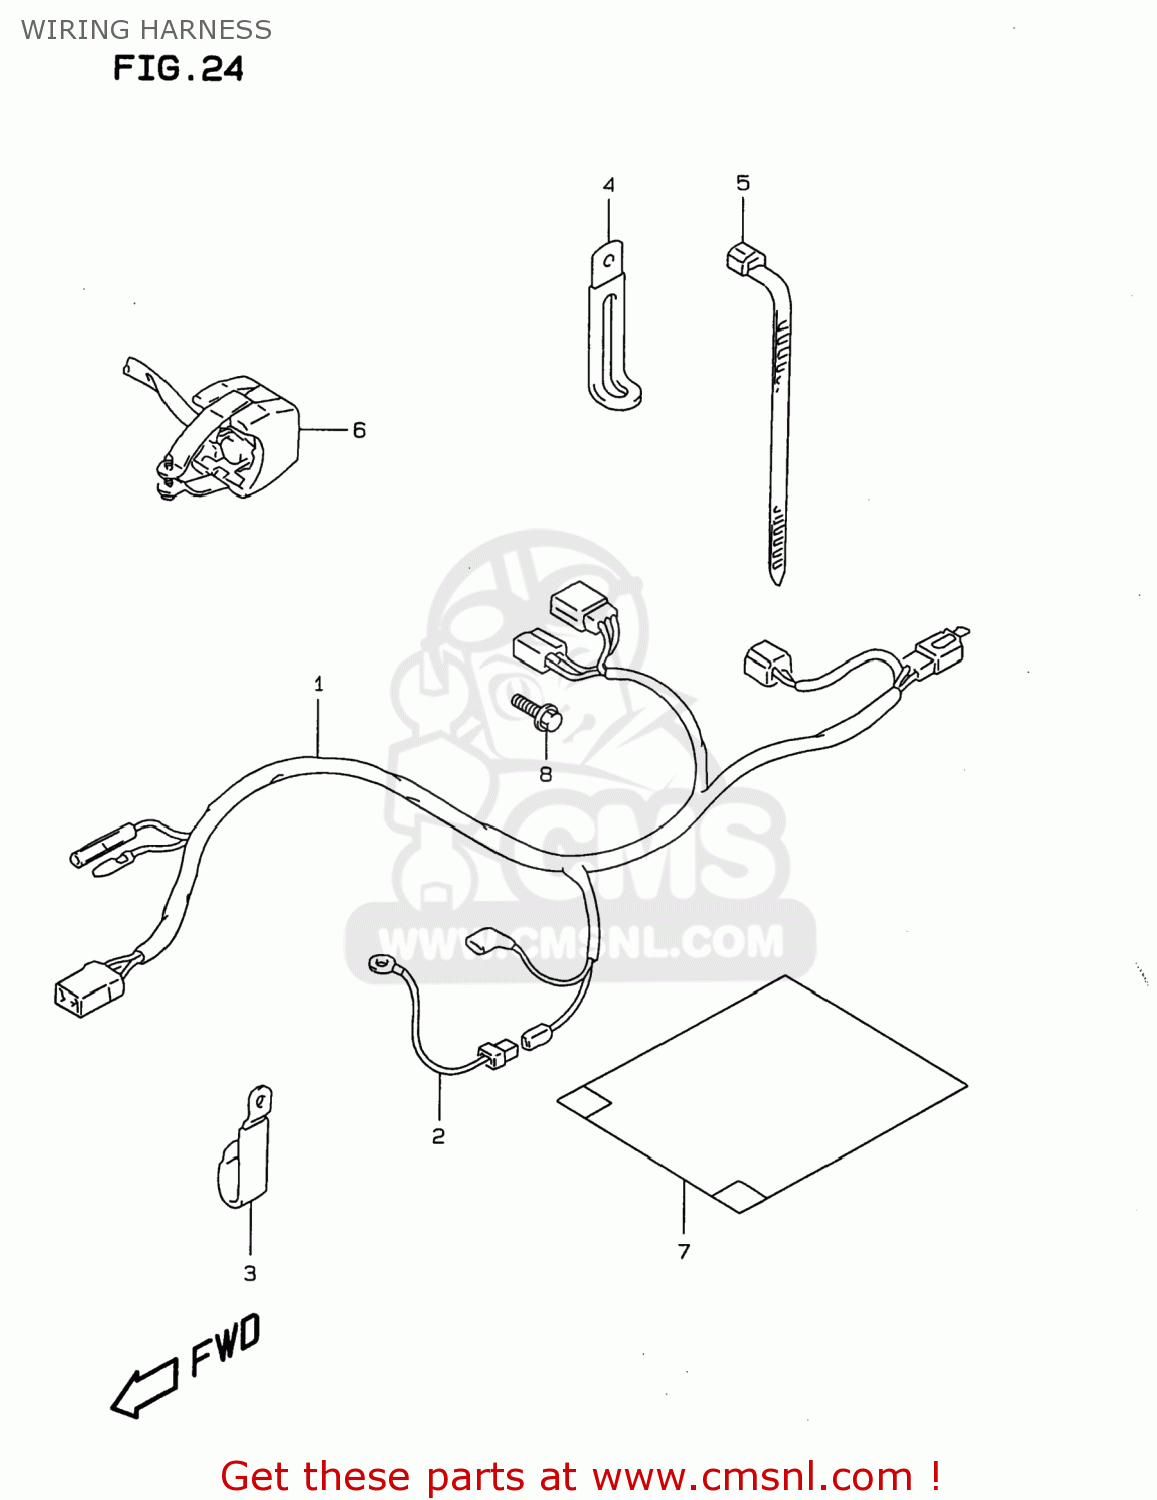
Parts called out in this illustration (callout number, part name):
1	HARNESS,WIRING
2	WIRE,REGULATOR EARTH LEAD
3	CLAMP
4	CLAMP L:62
5	CLAMP(L:95)
6	SWITCH ASSY,ENGINE STOP
7	COVER,WIRING HARNESS
8	BOLT
